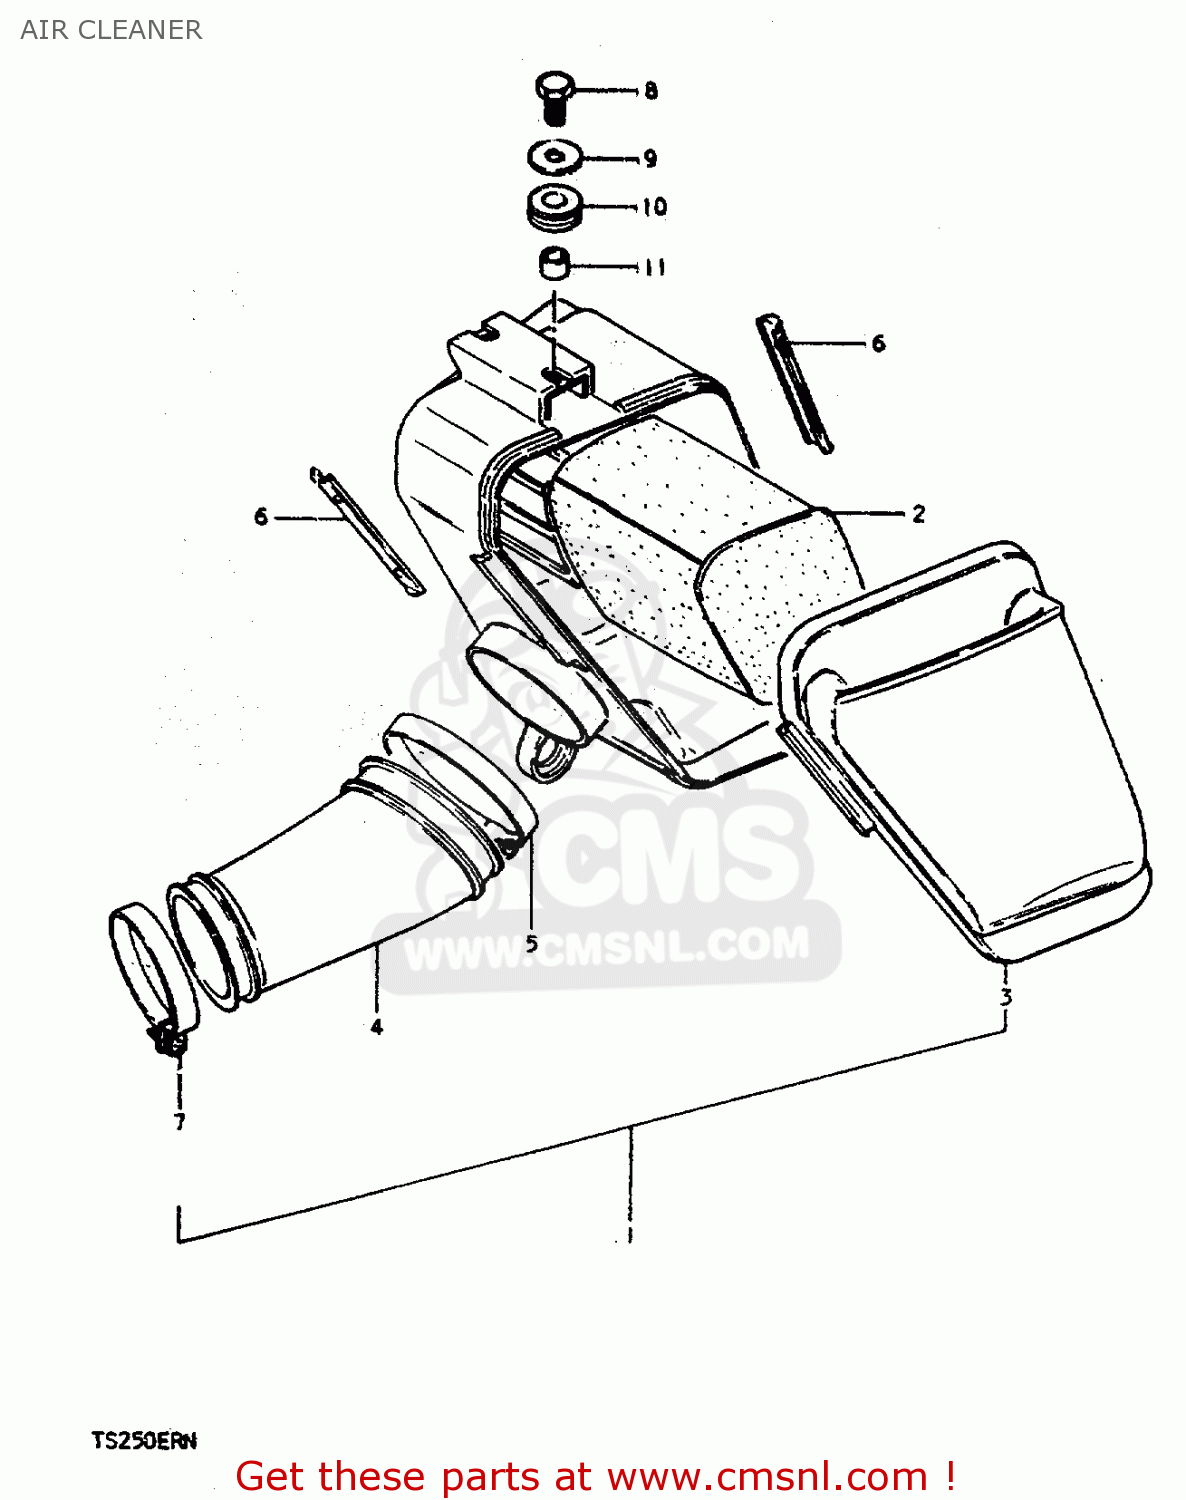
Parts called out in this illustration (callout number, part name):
1	CLEANER ASSEMBLY,AIR
2	FILTER
3	CAP,AIR CLEANER
4	OUTLET
5	CLAMP
6	SLIDER
7	CLAMP
8	BOLT, UPPER
9	WASHER (6.5X20X1.2)
10	CUSHION
11	SPACER (7X9X7)
